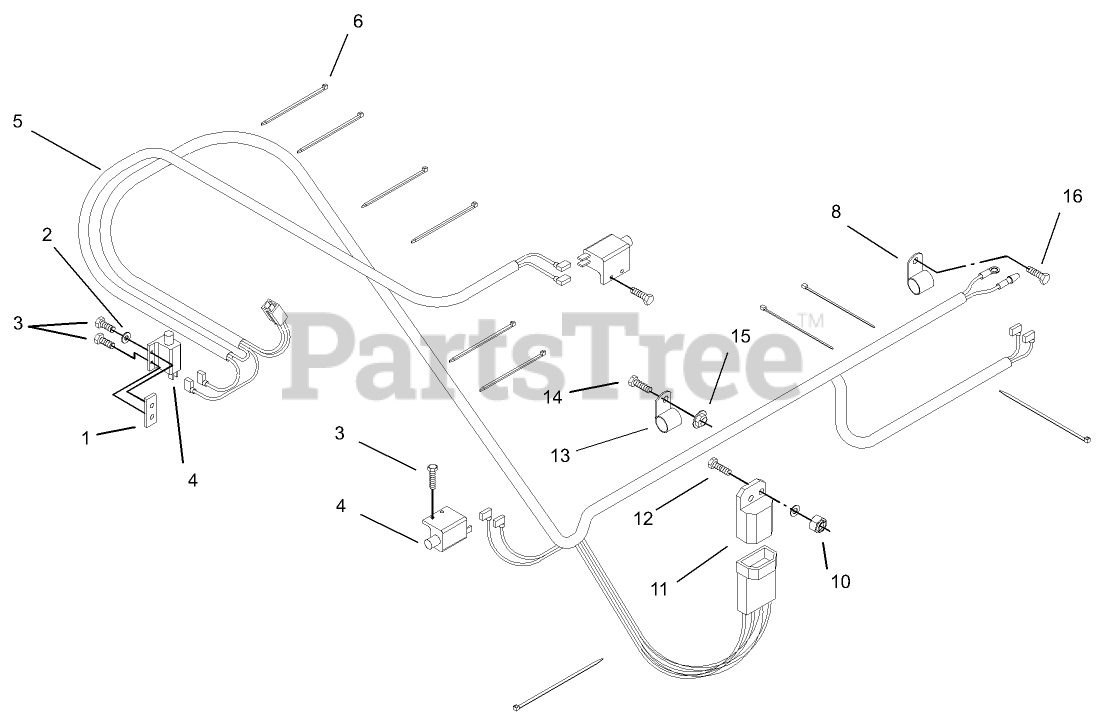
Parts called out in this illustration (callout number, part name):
1	PLATE-TAPPED
2	WASHER-FLAT
3	SCREW-PPH
4	SWITCH-OPEN, NORMALLY
5	Harness-Wire
6	TIE-CABLE
8	Clip-Loom
10	NUT-LOCK, NI
11	MODULE-INTERLOCK
12	SCREW-HH
13	CLIP-LOOM
14	SCREW-HH
15	NUT-HF
16	SCREW-HH
